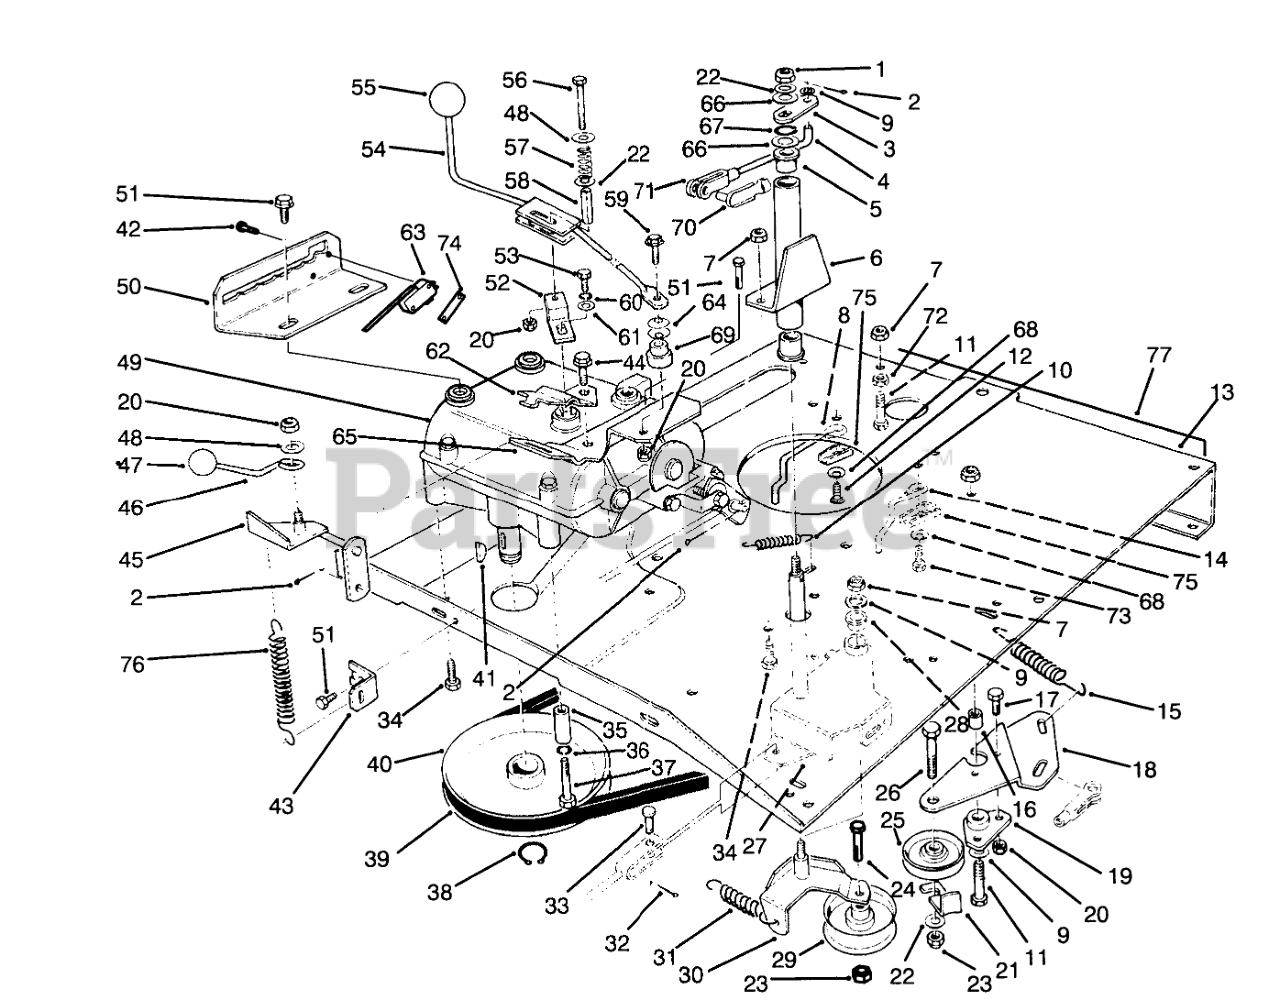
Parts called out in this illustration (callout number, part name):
1	NUT-LOCK, NI
2	PIN-COTTER
3	BRKT-DECK ENGAGE BLK
4	LINK-DECK ENGAGE
5	BUSHING-FLANGE
6	Tube W.A.-Pivot (Incl. Ref. #5)
7	NUT-LOCK, NI
8	ENG BELT GUIDE R.
9	WASHER-PLAIN
10	SPRING-RETURN, BRAKE
11	SCREW-HH
12	BOLT-CARR
13	PLATE-ENGINE
14	GUIDE-ENG. BELT L.
15	SPRING-TRACTION
16	SPACER-PIVOT
17	SCREW-HH
18	PLT-IDLER MTG
19	MOUNT-TRACTION PIVOT
20	NUT-LOCK, NI
21	RETAINER-BELT
22	WASHER-FLAT
23	NUT-LOCK, NI
24	SCREW-HH
25	PULLEY-IDLER
26	SCREW-HH
27	Bracket-Arm, Idler (Incl. Ref. #28)
28	BUSHING-FLANGE
29	PULLEY-IDLER
30	IDLER MTG PLT WA (BLACK)
31	SPRING-IDLER
32	SCREW-HSH
33	PIN-CLEVIS
34	SCREW-HH
35	GUIDE-BELT
36	WASHER-LOCK
37	SCREW-HH
38	RING-SNAP, EXTERNAL
39	67BELT, TRACTION DRIVE
40	PULLEY
41	KEY-WOODRUFF
42	SCREW-HH
43	BRKT-SPRING MT
44	SCREW-HWHTF
45	DECK ENGAGE LEVER WA (BLACK)
46	ROD-ENGAGE
47	KNOB-CONTROL
48	WASHER-FLAT
49	TRANSMISSION
50	Gate-Shift
51	SCREW-HWHTF
52	LEVER-SHIFT
53	SCREW-HH
54	SHIFT LEVER WA (BLACK)
56	SCREW-HH
57	SPRING-COMPRESSION
58	SPACER-SPLIT
59	SCREW-HH
60	WASHER-LOCK
61	WASHER-FLAT
62	BRKT-DECK ENG UPPER
63	SWITCH-MICRO
64	WASHER-BELLEVILLE
65	BRKT-DECK ENG. SHIFTER
66	WASHER
67	RING-RETAINING
68	WASHER-BELLEVILLE
69	SPACER-PIVOT
70	CLEVIS PIN ASM
71	CLEVIS-ADJ
72	NUT-JAM
73	SCREW-FLOW, TAPTITE
74	NUT-SPEED
75	ANCHOR-GUIDE, BELT
76	SPRING-DOOR
77	DECAL - REAR FRAME TORO
